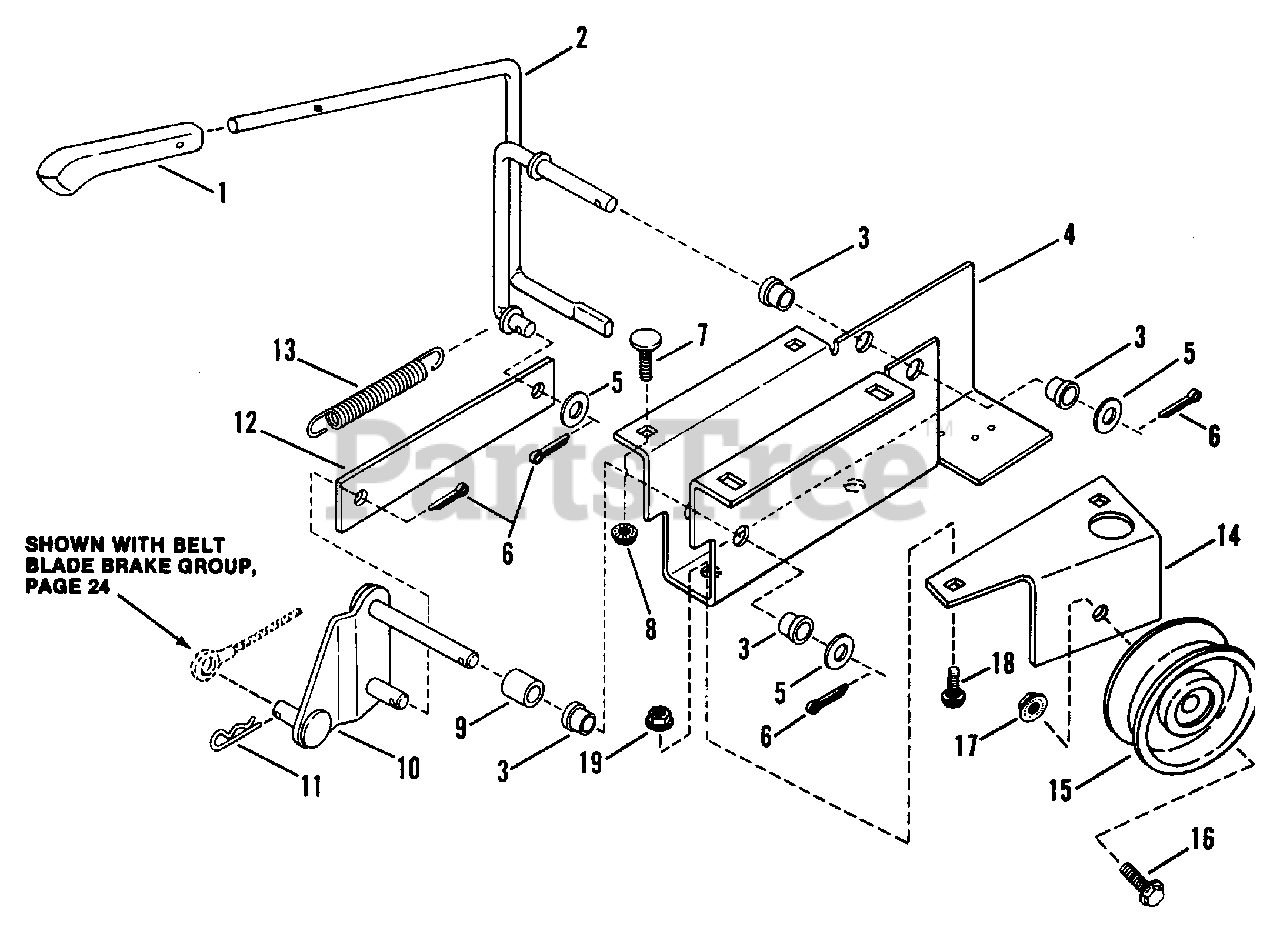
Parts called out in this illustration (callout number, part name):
1	KNOB, Handle 7/16"
2	HANDLE, Blade Engagement
3	BUSHING
4	BRACKET, Handle (No longer available)
5	WASHER, 3/8 SAE YZ
6	COTTER-PIN, 3/32 x 3/4"
7	BOLT, 1/4-20 x 5/8" Flat Head Carriage
8	LOCKNUT, 1/4-20 Hex Flange
9	SPACER .625 OD x .380 ID x .560 L
10	PIVOT ARM ASSEMBLY
11	PIN, Hair
13	SPRING, Return
14	BRACKET, Idler Support
15	PULLEY, Idler 2.75" OD
16	BOLT, 3/8-16 x 1-3/4" Hex Flange Lock
17	NUT, 3/8-16 Hex Lock
18	BOLT, 5/16-18 x 1/2" Short Neck Carriage
19	NUT, 5/16-18 Hex Lock Flanged
